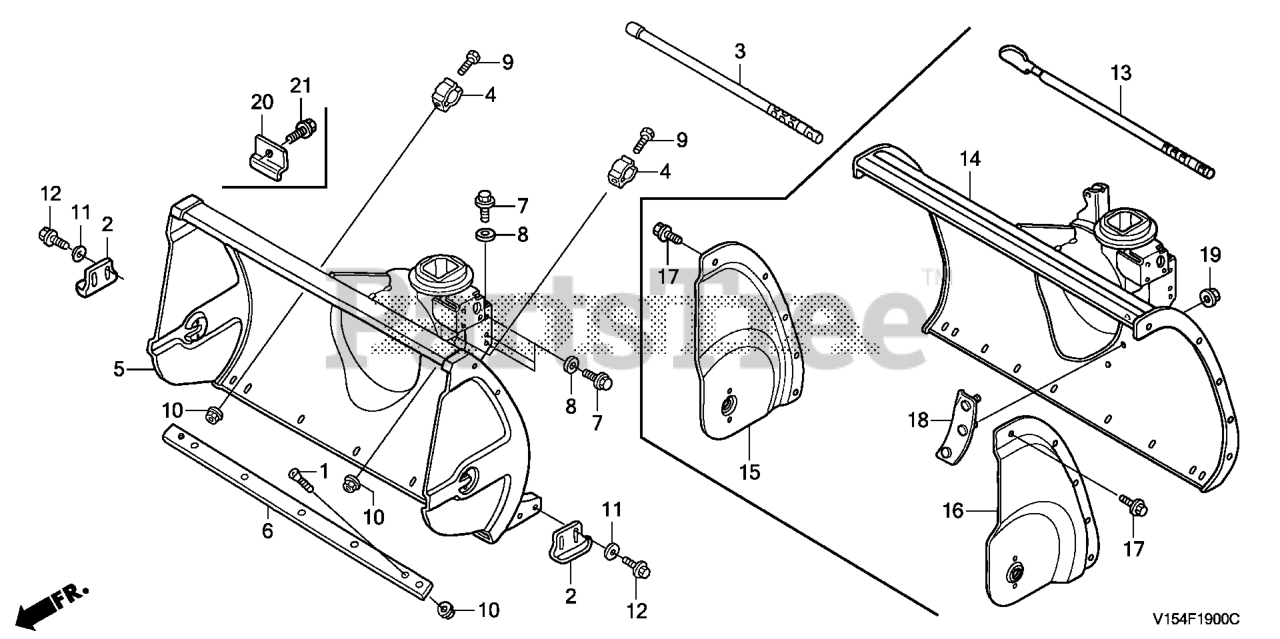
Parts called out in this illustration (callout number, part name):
1	BOLT, DOOR LOCK STRIKER
2	SKID, AUGER
4	BRACKET, SNOW DROP BAR
5	HOUSING, AUGER
6	GUARD, AUGER HOUSING
9	BOLT, HEX. (8X16)
10	NUT, FLANGE (8MM)
11	WASHER, PLAIN (8MM)
12	BOLT, FLANGE (8X20) Use up to Engine SN 1609606.
13	BAR, SNOW DROP
18	GUARD, AUGER (UPPER)
19	NUT, FLANGE (8MM)
20	GUIDE, ROLLING
21	BOLT, FLANGE (10X16)
